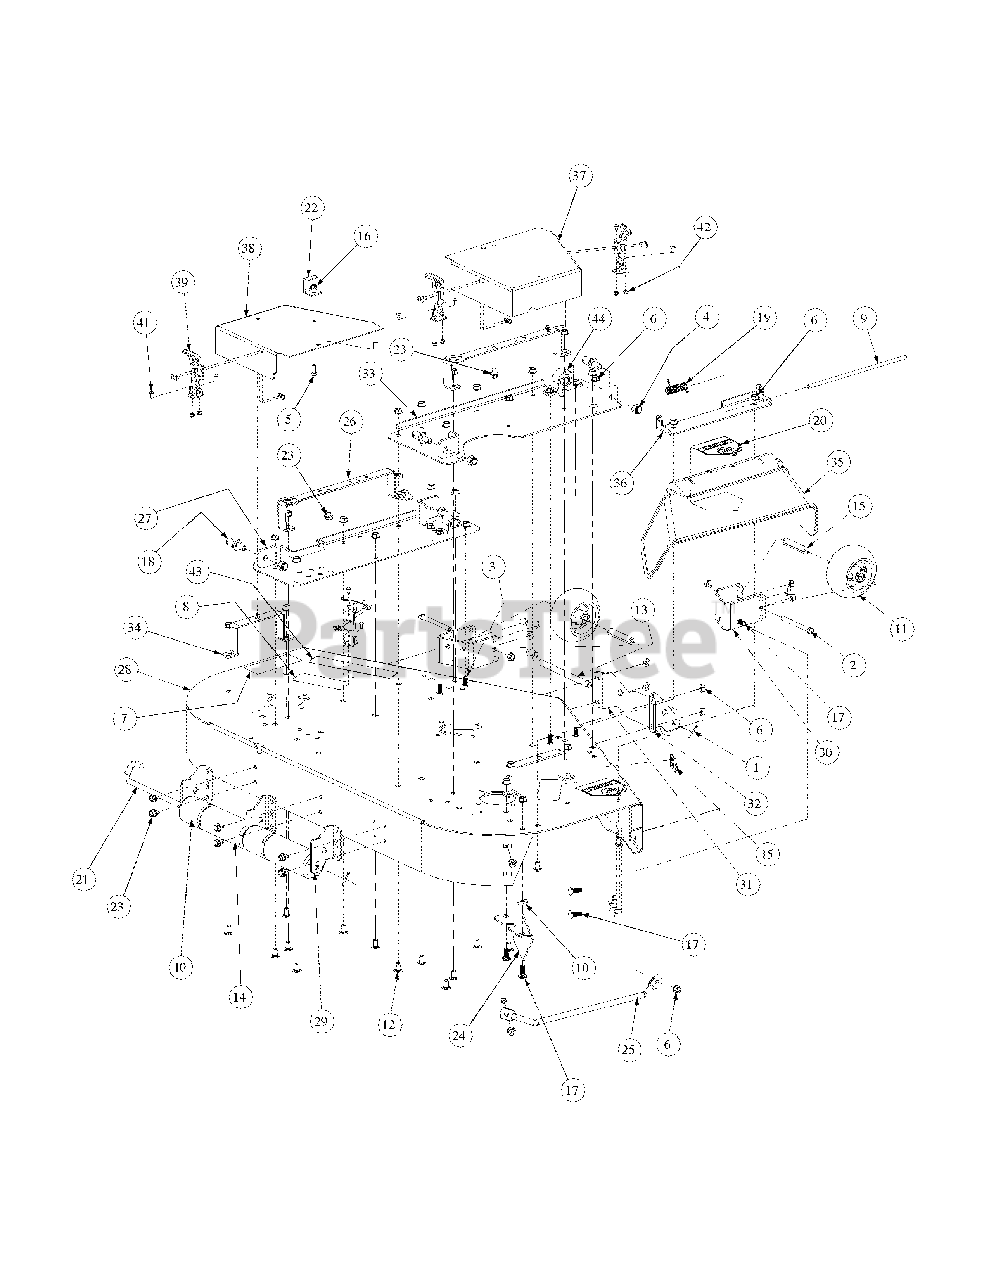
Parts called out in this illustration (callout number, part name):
1	Cotter Pin, .125 Dia. x 1.0
2	Hex Cap Screw, 3/8-16, 3.75
3	Carriage Screw, 3/8-16 x 1.25
4	Lock Nut, Nylon Insert, 1/2-13
5	Hex Cap Screw, 5/16-18 x 3/4
6	Flange Lock Hex Nut, 3/8-16
7	Decal Rotating Blade
8	Decal Warning Shield Missing
9	Chute Deflector Rod
10	Idler Washer
11	Complete Wheel, 5.00 Dia
12	Carriage Bolt, 3/8-16 x .75 Lg
13	Roller Pin, 1/2 Dia x 7.31 Lg
14	Front Roller
15	Wheel Spacer
16	Hex Flange Lock Nut, 5/16-18
17	Carriage Bolt, 3/8-16 x 1
18	Pin, 5/8 Dia. x 1.2 Lg.
19	Torsion Spring, 0.4 ID x 2.16 LG
20	Decal, Danger Hands and Feet
21	Roller Rod
22	Bracket Stop Tension Rod
23	Hex Index Washer Screw, 3/8-16, .05
24	Fabricated Deck, Chute Bracket
25	Fabricated Deck Finger Guard
26	Fabricated Belt Support Cover
27	Left Hand Deck Bracket Assembly
28	48" Fabricated Deck Assembly
29	Fabricted Deck Roller Mount Bracket
30	Front Anti-Scalp Wheel Mount Bracket
33	Right Hand Deck Bracket Assembly
34	Outer Belt Cover Support Assembly
35	Deflector Chute
36	Deflector Chute Bracket
37	Right Hand Belt Cover
38	Left Hand Belt Cover
39	Latch Drawing, T-Handle
41	Phillip Head Screw, 10-32
42	Lock Nut, Nylon Insert, 10-32
44	Pillow Block
45	Decal, 48"
